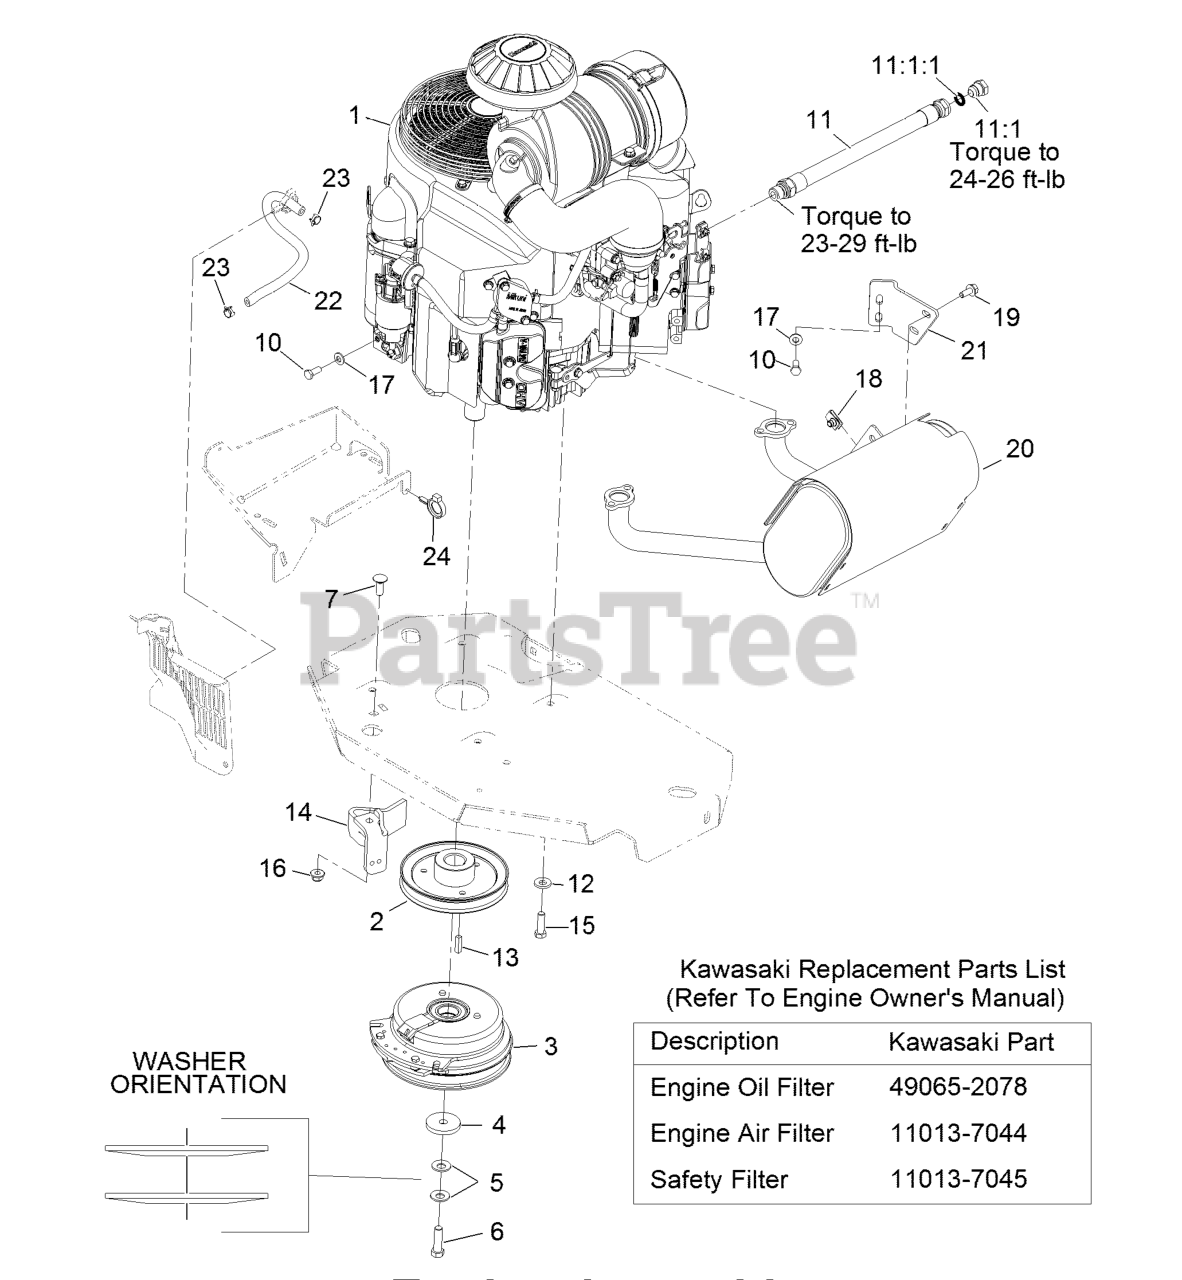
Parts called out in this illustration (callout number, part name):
2	SHEAVE
3	CLUTCH KIT
4	WASHER-CLUTCH
5	WASHER-SPRING
6	SCREW-HH 7/16-20 X 1 1/2 W/LOCTITE
7	SCREW-CARR
10	SCREW-HH
11	ENGINE OIL DRAIN HOSE ASM
11:1	PLUG-HH
11:1:1	O-RING
12	WASHER-BELLEVILLE
14	CLUTCH-ANCHOR
15	SCREW-HH
16	NUT-HF, NI
17	WASHER-SPRING
19	SCREW-HHF
20	MUFFLER
21	BRACKET-MUFFLER
22	HOSE-FUEL
23	CLAMP-HOSE
24	CLAMP-HOSE
